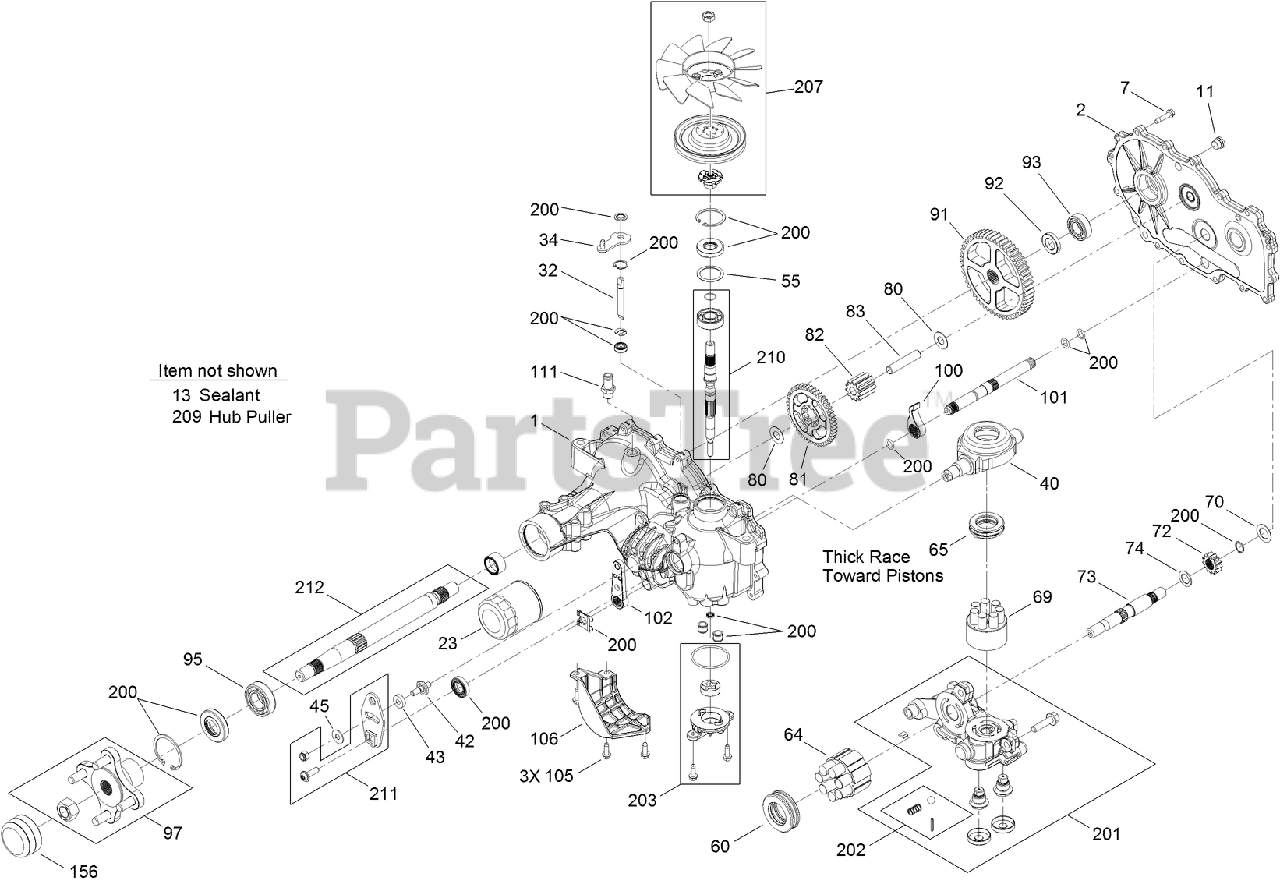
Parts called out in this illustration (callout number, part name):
1	MAIN HOUSING KIT
2	RH HOUSING SIDE KIT
7	SCREW-HHF
11	PLUG-THREAD, STRAIGHT
23	ELEMENT-OIL FILTER, HYD
32	ROD-BYPASS
34	ARM-BYPASS
40	SWASHPLATE-TRUNNION
43	PUCK-FRICTION
45	WASHER
55	SPACER
60	BEARING-THRUST
64	MOTOR CYLINDER BLOCK KIT
65	BEARING-THRUST
69	PUMP BLOCK ASM
70	WASHER-FLAT
72	GEAR-13T
73	SHAFT-MOTOR
74	WASHER
80	WASHER
81	GEAR-46T
82	GEAR-11T
83	PIN-JACKSHAFT
91	GEAR-54T
92	SPACER
93	BEARING-BALL
95	BEARING-BALL
97	HUB KIT
100	PAWL-BRAKE
101	BRAKE SHAFT KIT
102	HANDLE-BRAKE
106	GUARD-FILTER, RH
111	ADAPTER-STRAIGHT
156	COVER-NUT, AXLE
200	SEAL KIT
201	RH CENTER SECTION CHARGE KIT
202	CHARGE RELIEF KIT
203	CHARGE KIT
207	FAN AND PULLEY KIT
210	INPUT SHAFT KIT
211	CONTROL ARM KIT
212	AXLE SHAFT KIT
